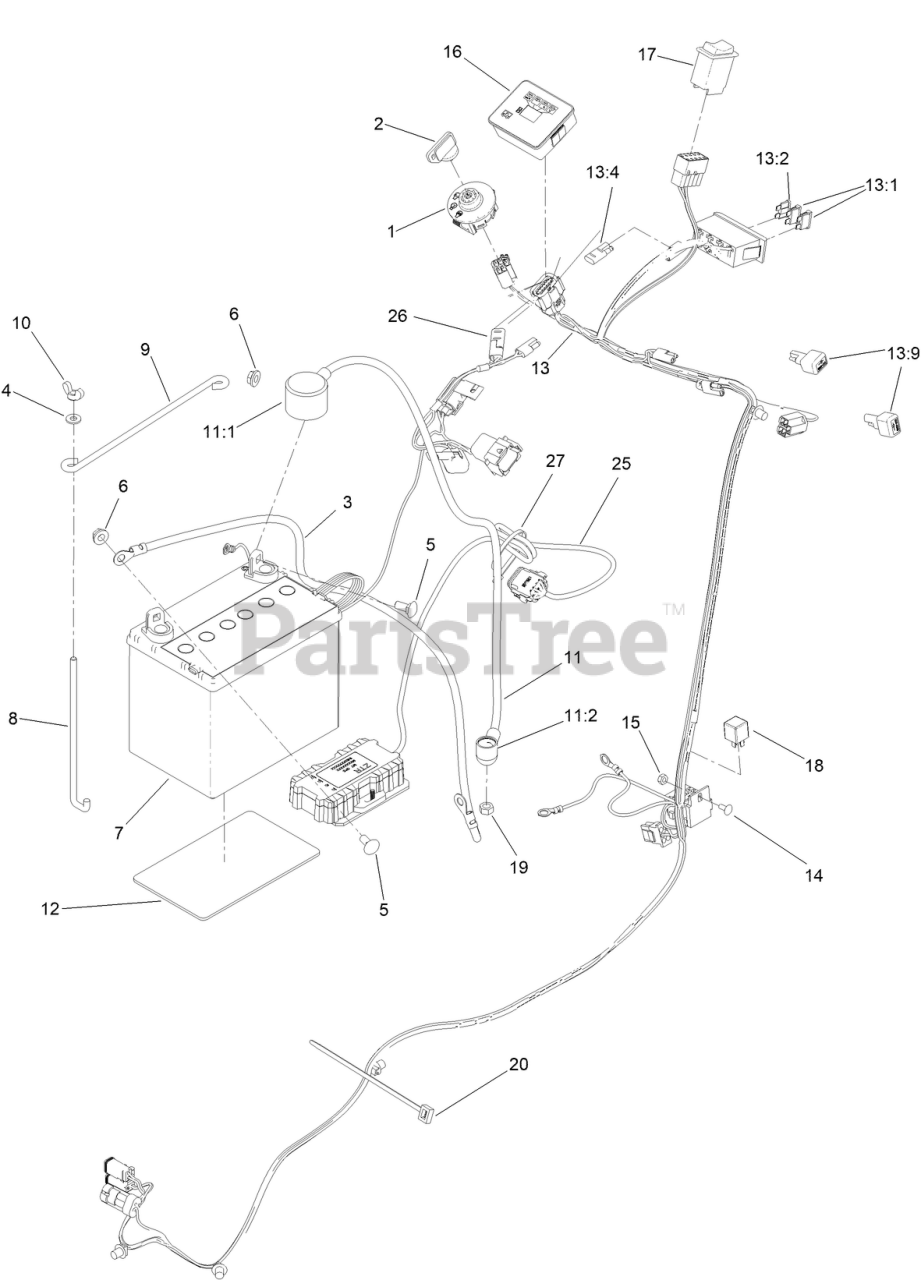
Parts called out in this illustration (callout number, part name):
1	SWITCH-IGNITION
2	KEY-IGNITION
3	CABLE-BATTERY, NEGATIVE
4	WASHER-FLAT
5	BOLT-CARR
6	NUT-HF
7	BATTERY (340 CCA, WET)
8	POST-BATTERY
9	ROD-HOLD DOWN, BATTERY
10	NUT-WING
11	POSITIVE BATTERY CABLE ASM
11:1	INSULATOR-BATTERY
11:2	INSULATOR-SOLENOID
12	PAD-SKID, ANTI
13	HARNESS-WIRE
13:1	FUSE-BLADE, 15 AMP
13:2	FUSE-BLADE, 7.5 AMP
13:4	CAP-PLUG
14	BOLT-CARR
15	NUT-LOCK, NI
16	MODULE, HOUR METER
17	SWITCH-ROCKER, 2 POLE
19	NUT-HEX
20	TIE-CABLE
25	M7L-LITE ZTR KIT ASM
26	HARNESS-WIRE, MACHINE ZTR
27	TIE-CABLE
